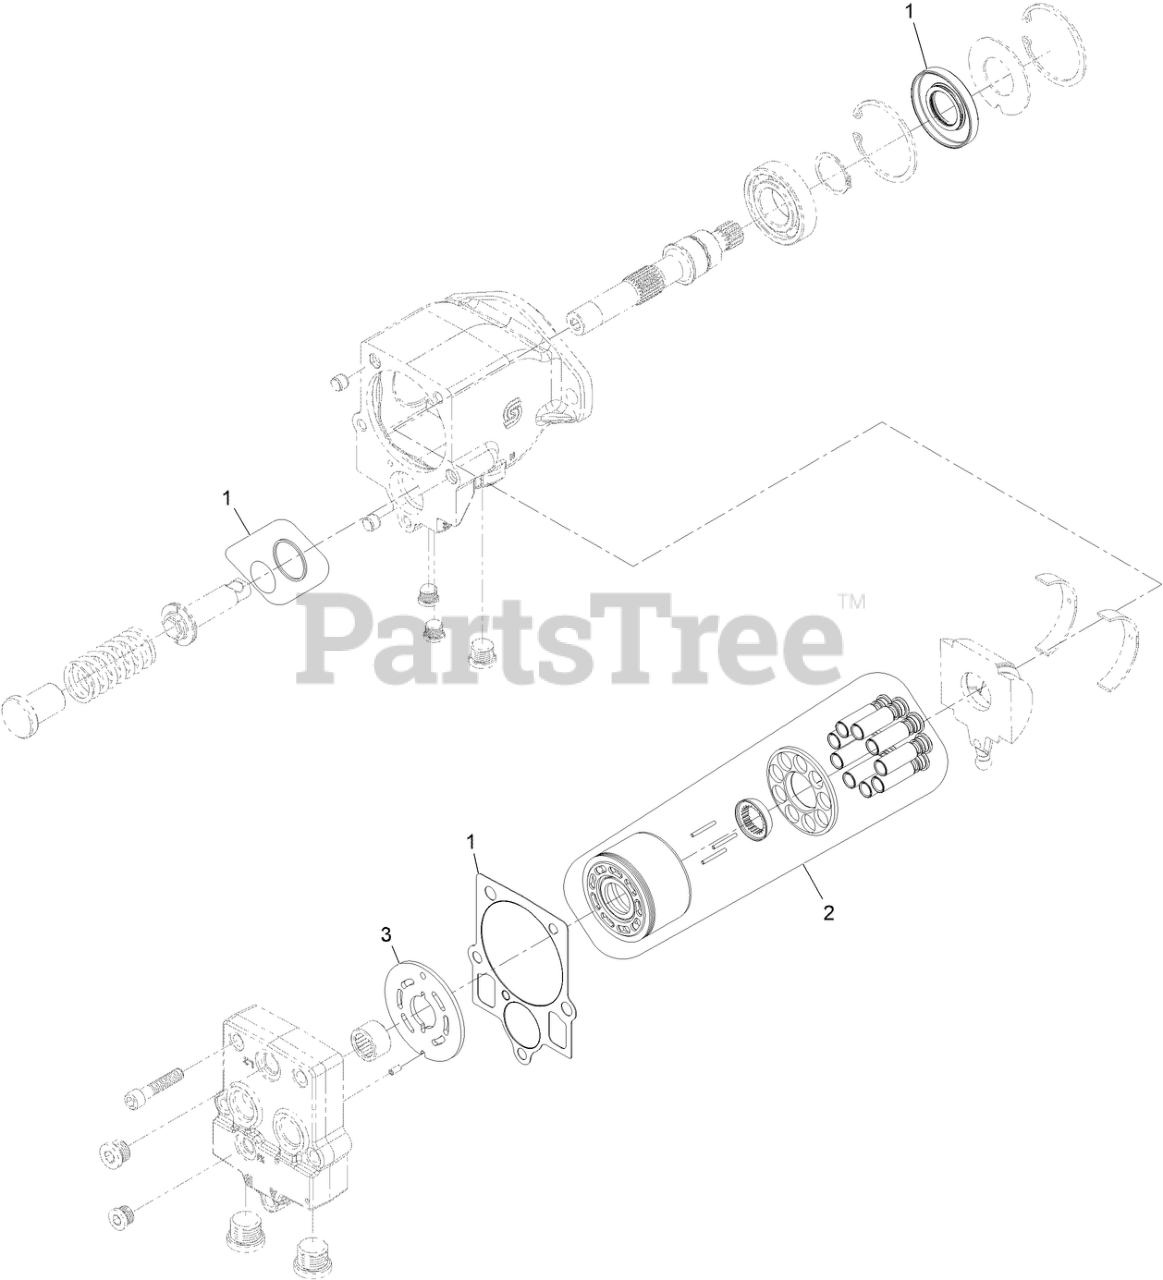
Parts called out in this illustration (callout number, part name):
1	SEAL KIT-HYD MOTOR
2	CYLINDER BLOCK KIT
3	PLATE-VALVE
